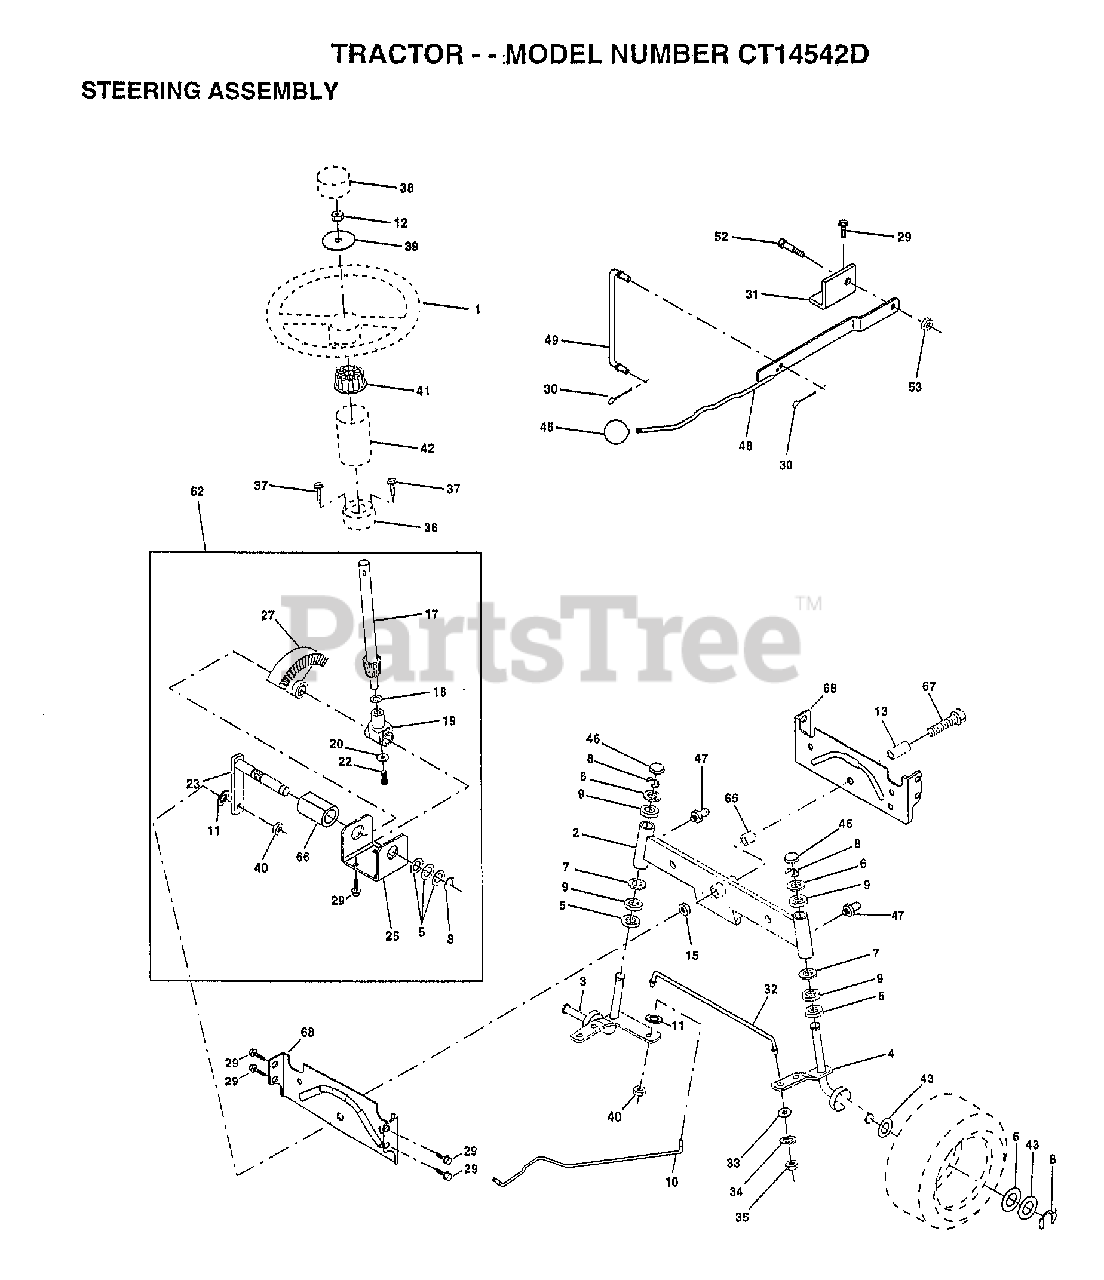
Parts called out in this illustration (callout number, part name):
1	WHEEL STR AYP BLK
2	AXLE ASM
3	SPINDLE.ASM.LH
4	"SPINDLE ASM,RH"
5	WASHER .T
6	WASHER
7	WASHER
8	RING
9	COL. SRTG. BEAR.
10	DRAGLINK-STAMPED
11	LOCKWASHER
13	BEARING AXLE
15	"NUT-LOC,FLANGE LT"
17	SHAFT ASM STEERNG
18	THRUST WASHER
19	SUPPORT.SHAFT
21	LOCKWASHER
22	SCREW HEX SOC1/4-
25	BRKT-STEERING
27	GEAR SECTOR
29	SCREW
30	COTTER PIN
31	BRKT.PVT.MAN.LVR.
32	ROD.TIE.19.75
33	WASHER M
34	LOCKWASHER
35	NUT.LOCK.5/16-24
36	BUSHING.STRG.3/4
37	"SCREW-TT,10-32 FL"
38	CAP STEER AYP
39	WASHER
40	GRIPCO NUT
41	ADAPTER LT
42	BOOT SHAFT STEER
43	WASHER
45	KNOB T (1/2-HOLE)
46	CAP
47	ZERK M
48	LEVER.ASM.CLUTCH
49	LINK CLTCH W/NUTS
52	"BOLT, SHOULDER LT"
62	KIT STEERING ASM
65	SPACER AXLE
66	"BEARING-ARM,PITMA"
67	BOLT
68	BRACE AXLE
